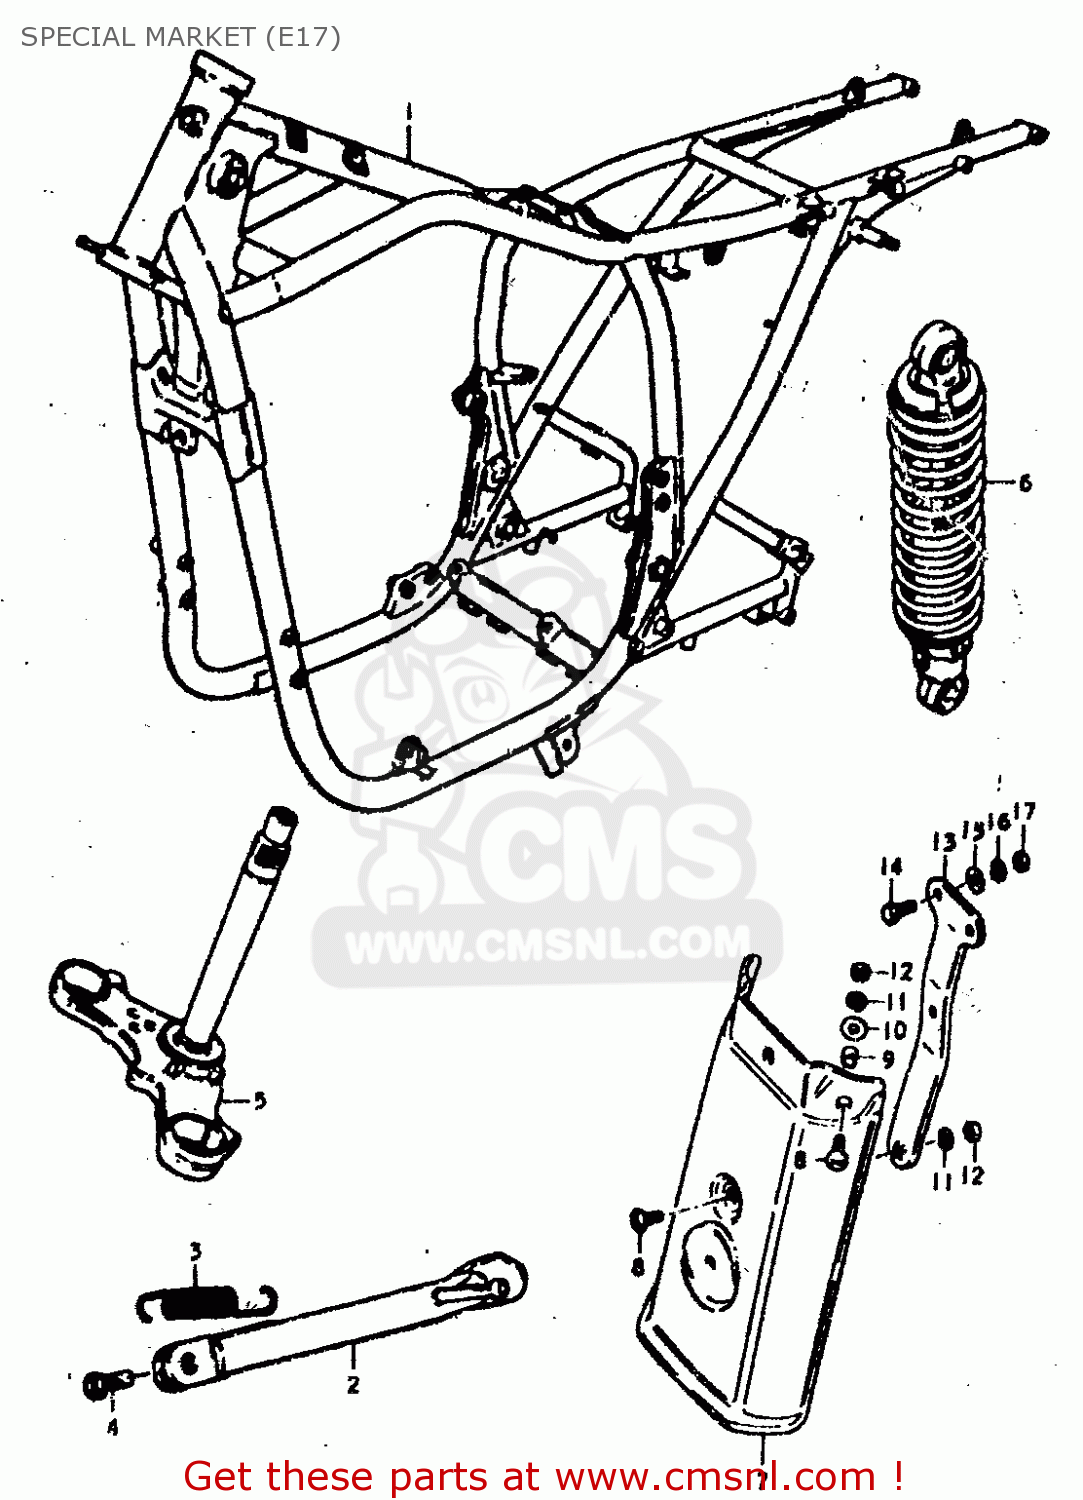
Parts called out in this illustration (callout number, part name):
2	STAND,PROP
3	SPRING
4	BOLT
5	STEERING STEM
6	SHOCK ABSORBER, REAR
7	EXTENSION,REAR FENDER
8	SCREW (6X15)
9	SPACER(6.2X8.3X5.7)
10	WASHER(6.5X18X1)
11	LOCK WASHER
12	NUT
13	BRACE, REAR FENDER EXTENSION
